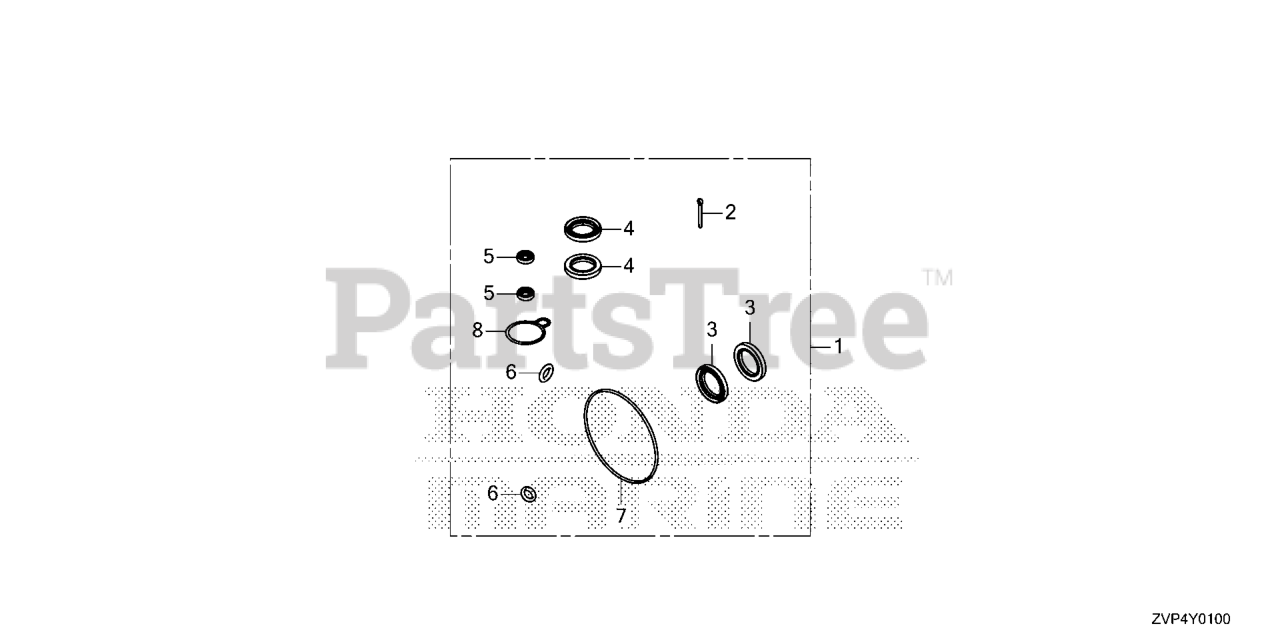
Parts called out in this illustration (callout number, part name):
1	SEAL KIT, GEAR CASE
2	PIN, SPLIT (4.0)
3	SEAL (35X50X7)
4	SEAL, WATER (30X45X7)
5	SEAL, WATER (12X21X6)
6	O-RING (6.9X1.45)
7	O-RING (121X3.1)
8	O-RING, SHIFT ROD
